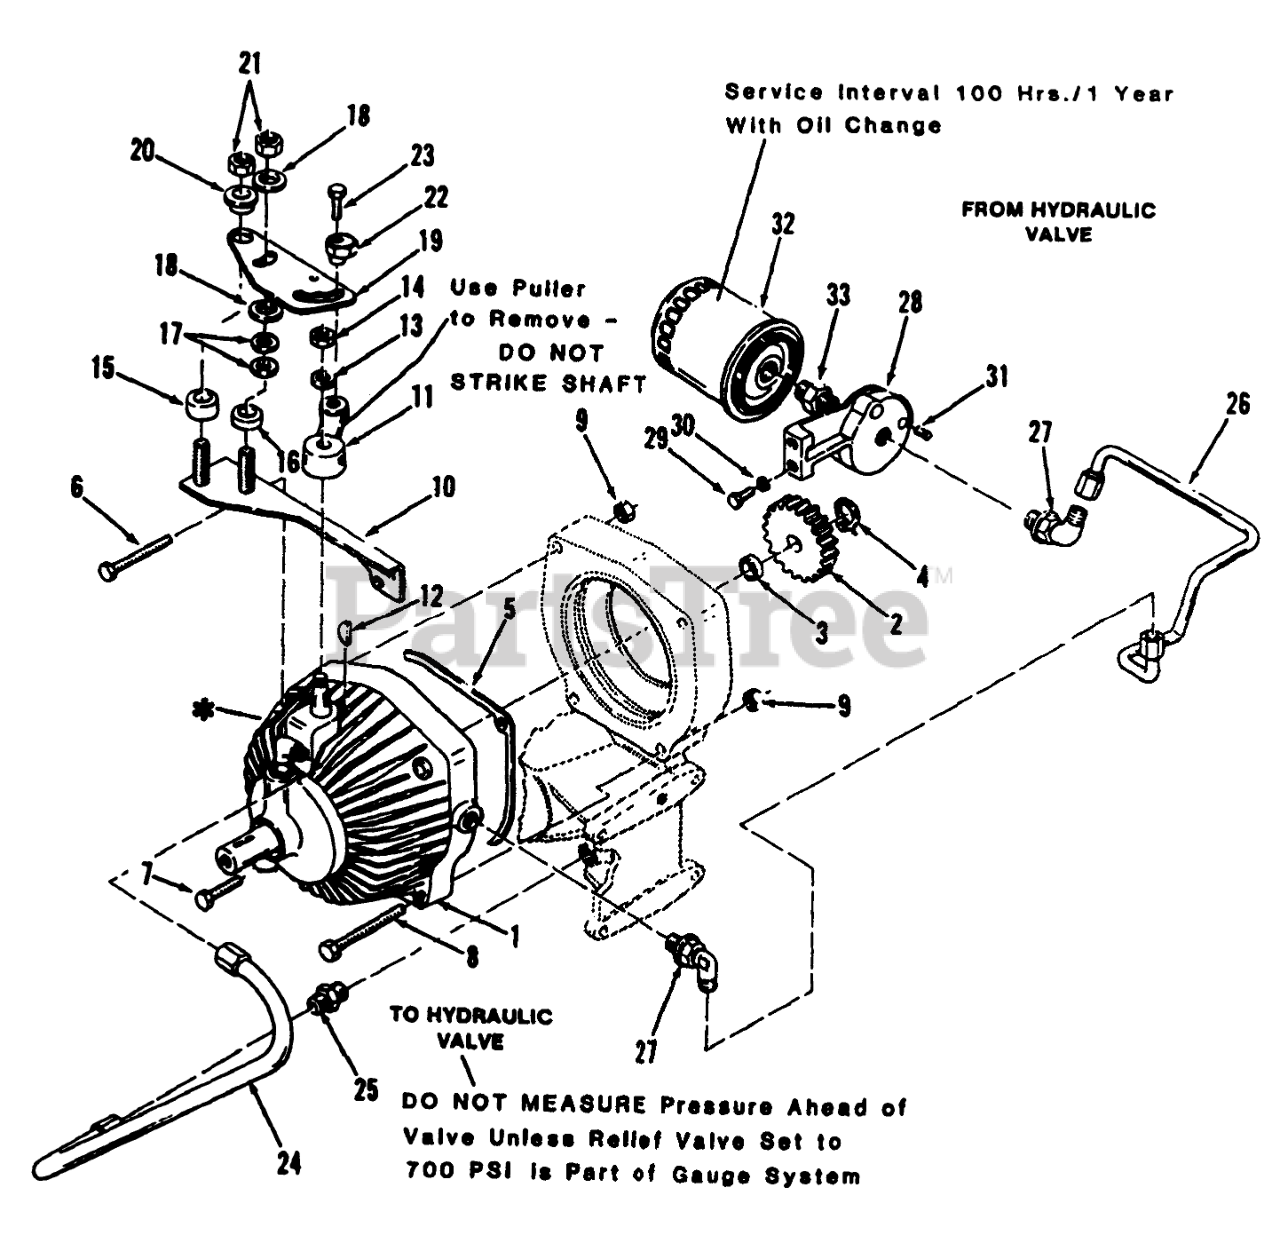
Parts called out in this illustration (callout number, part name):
1	Pump & Motor
2	GEAR 20 TEETH DRIVE
3	SPACER GEAR
4	RING-SNAP, EXTERNAL
5	GASKET
6	SCREW-HH
7	SCREW-HH
8	SCREW-HH
9	NUT-LOCK, NI
10	ASSY-PLATE B
11	ARM-SPEED CONTROLB
12	KEY-WOODRUFF
13	NUT-LOCK, NI
14	NUT-LOCK, NI
15	SPACER-PIVOT
16	SPACER-FRICTION
17	WASHER-SPRING DISC
18	FRICTION WASHER
19	CAM-SPEED CONTROL (NS)
20	CAM-SPACER
23	SCREW-HH
24	ASSY-TUBE SUCTION
25	FITTING-TUBE
26	ASS'Y-TUBE FILTER
27	ELBOW
28	BASE-FILTER
29	SCREW-HH
30	WASHER-LOCK
32	OIL FILTER ASM
33	FITTING
